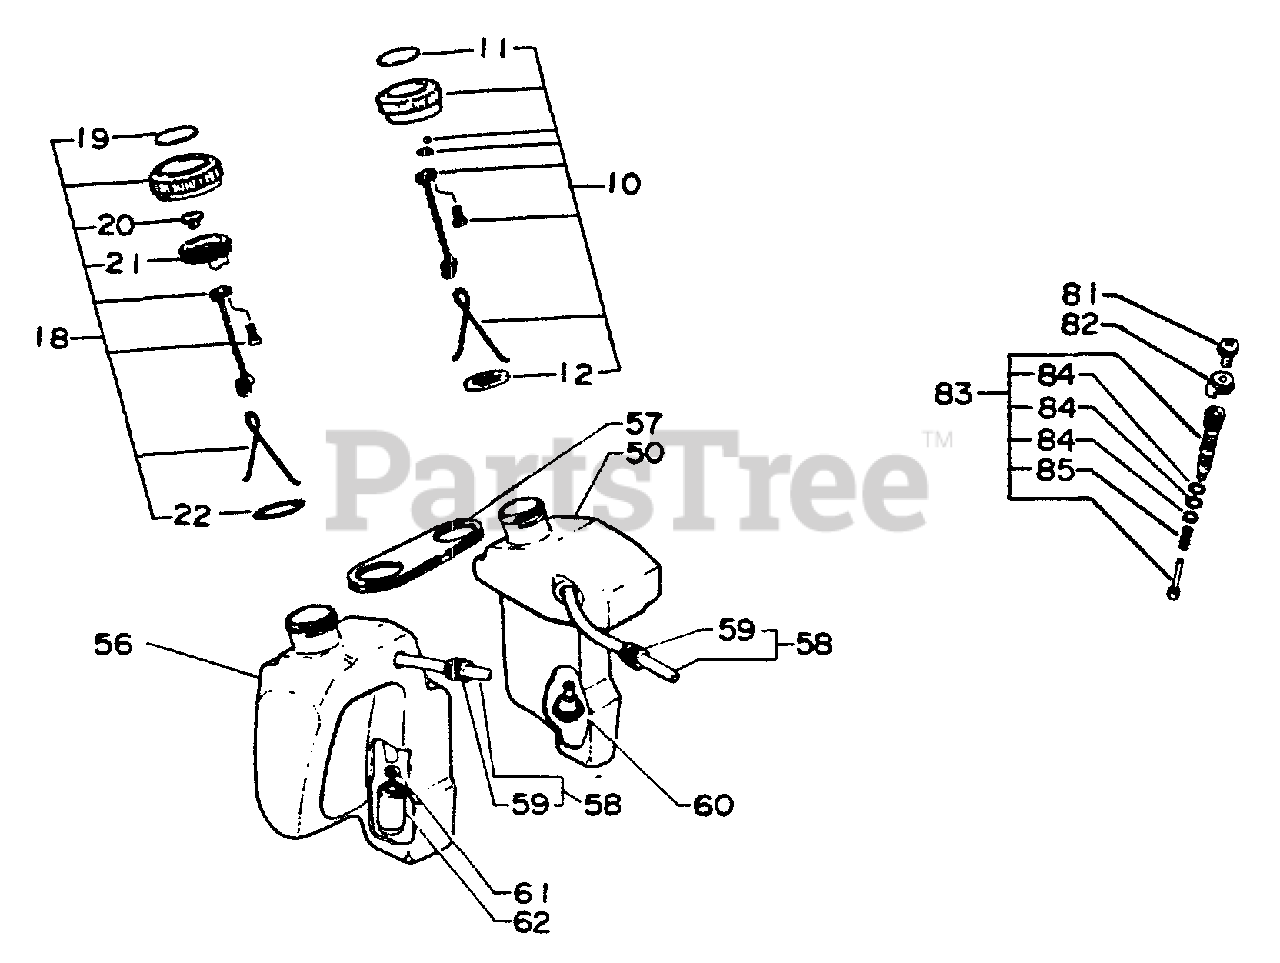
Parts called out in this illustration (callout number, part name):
10	CAP ASSY
11	LABEL - CHAIN OIL
12	GASKET, CAP
18	CAP ASSY
19	LABEL - FUEL MIX
21	HOLDER, VENT
22	O-RING - 22
50	TANK, OIL
56	TANK, FUEL
57	CONNECTOR
58	FUEL PIPE KIT
60	FILTER, OIL
61	WASHER - 5
62	FILTER, FUEL
81	SCREW - 5X10
82	LOCKWASHER
83	AUTO-OILER ASSY
84	O-RING - 5
